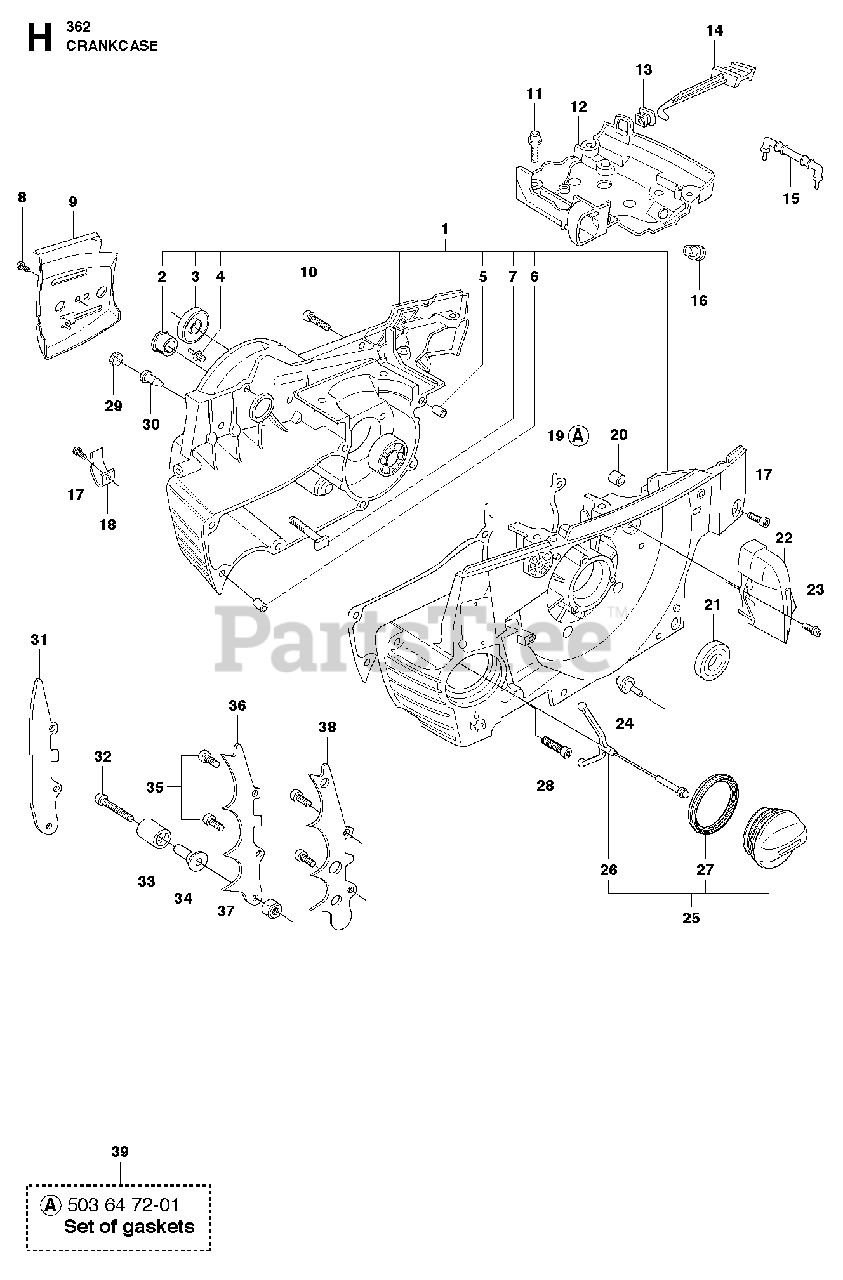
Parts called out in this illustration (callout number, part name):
1	RP CRANKCASE
2	BUSHING
3	SEAL
4	PIN
5	SLEEVE
6	SLEEVE
7	BOLT
11	SCREW
12	BASE
15	SPACER
17	SCREW IHSCM
18	CHAIN CATCHER
19	GASKET
23	SCREW
25	TANK CAP
26	TANK LOCK
27	SEALING
29	PLUG
30	VALVE-CHECK (DUCKBILL)
32	SCREW IHSCFM
34	CHAIN CATCHER
36	FELLING DOG
38	FELLING DOG
39	GASKET SET
